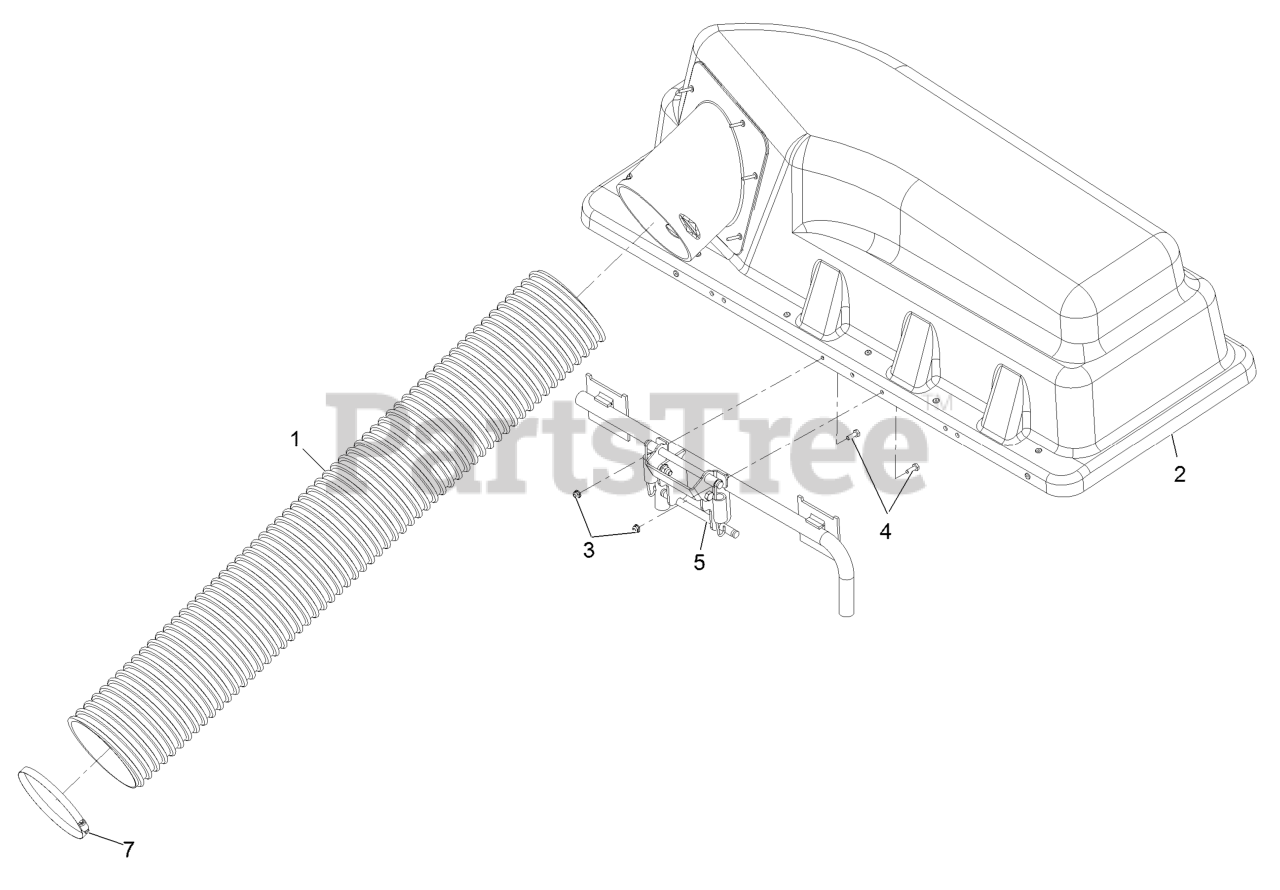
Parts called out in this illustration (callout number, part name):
1	HOSE,FLEXIBLE
2	ASM,BAGGER HOOD
4	SCREW-HH
5	ASM,BAGGER MOUNT
